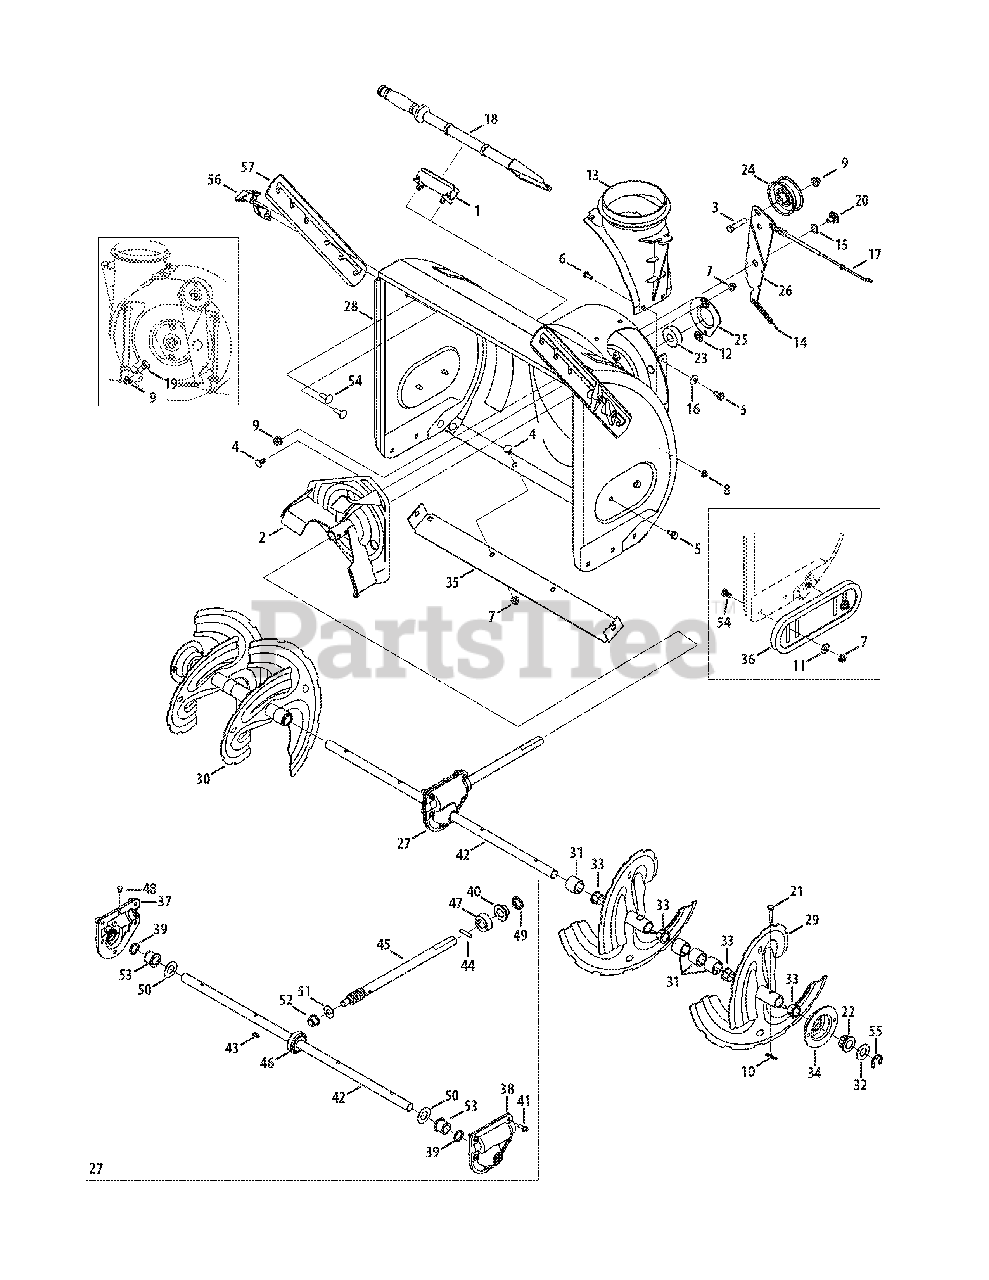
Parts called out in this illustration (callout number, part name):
1	Snow Removal Tool Mount
2	Impeller Assembly, 12" Dia.
3	Hex Screw, 3/8-16, 1.75, Gr5
4	Bolt, Carriage, 5/16-18, .750 Gr1
5	Screw, 5/16-18, 0.750
6	Screw, Carriage, 1/4-20, .750, Gr5
7	Nut, Flange Lock, 5/16-18, Nylon
8	Nut, Flange Lock, 1/4-20, Nylon
9	Nut, Flange Lock, 3/8-16, Nylon
10	Cotter Pin, Bow-tie
11	Washer, Flat, .349 x .879 x .063
12	Nut, Push-on, .25 Dia
13	Chute, Adapter 5" Dia
14	Spring, Extension, .38 OD x 4.59
15	Washer, Wave, .625 x .885 x .015
16	Washer, Bell, .340 x .872 x .060
17	Clutch Cable, Auger, 47.23"
18	Snow Removal Tool
19	Screw, Shoulder, .498 x .34, 3/8-16
20	Screw, Shoulder, .625 x .17, 3/8-16
21	Shear Pin, .25 x 1.50
22	Bearing, Hex Flange x .75 ID
23	Bearing, Ball, .75 ID x 1.85 OD
24	Flat Pulley, Idler, 2.75 OD
25	Housing, Bearing, 1.85 ID
26	Bracket, Auger Idler w/ Brake
27	Gearbox Assembly, Auger, 28"
28	Housing Assembly, Auger 28"
29	Spiral Assembly, LH
30	Spiral Assembly, RH
31	Spacer, 1.25 OD x .75 ID x 1.00
32	Washer, Flat, .76 x 1.49 x .06
33	Bushing, Flange, .80 ID x .91 OD
34	Housing, 1" Hex Bearing
35	Shave Plate, 2.25 x 27.66
36	Polymer Slide Shoe, Deluxe
36	Polymer Reversible Shoe Kit
37	Housing, Auger, RH Reduced
38	Housing, Auger, LH Reduced
39	Seal, Oil, .750 x 1.00 x .125
40	Bearing, Flange, .75 x 1.0 x .59
41	Screw, Self-tapping, 1/4-20, 0.750
42	Axle, Auger, 28"
43	Key, Hi-pro 3/16 x 5/8
44	Pin, Dowel, .25 OD x 1.2
45	Shaft, Worm .75 OD
46	Gear, Worm 20T
47	Collar, Thrust
48	Plug, 1/4 x .437
49	Seal, Oil, .75 x 1 x .131
50	Washer, Flat, .760 ID x 1.5 OD
51	Washer, Flat, .51 x 1.12
52	Bearing, Flange, .75 x 1.0 x .925
53	Bearing, Flange, .75 x 1.00 x .975
54	Screw, Carriage, 5/16-18 x 1.00
55	E-Ring
56	Wing Knob
57	Drift Cutter
